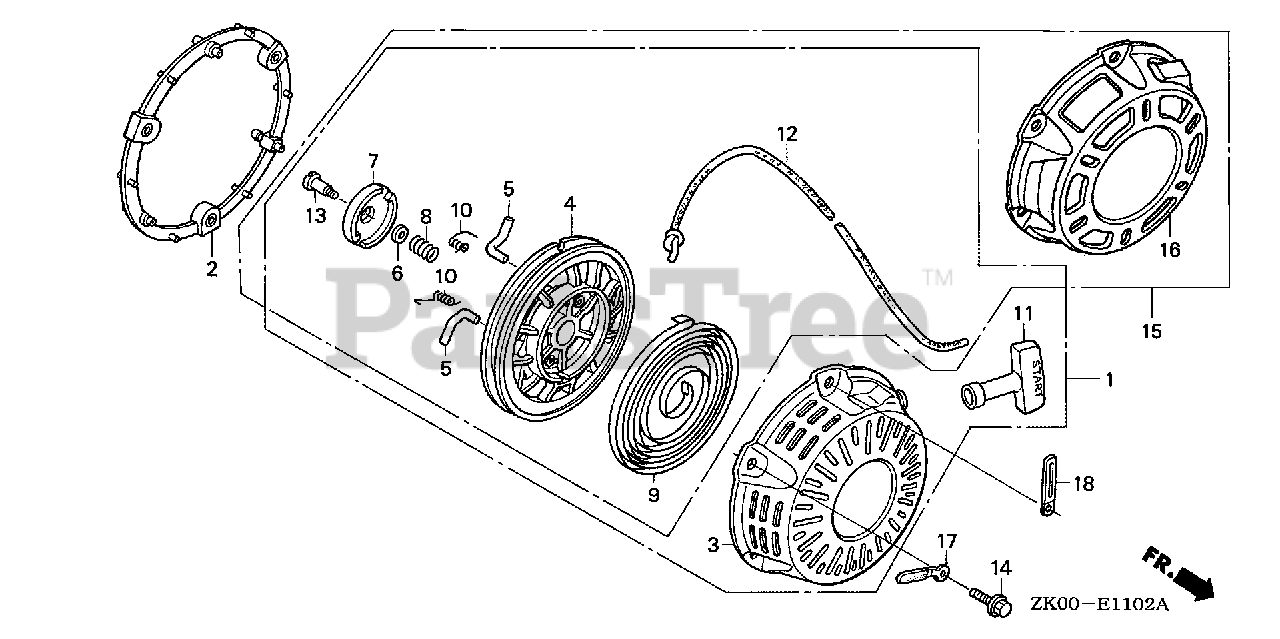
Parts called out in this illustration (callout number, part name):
1	STARTER ASSY., RECOIL *R280* (POWER RED)
2	SPACER, RECOIL STARTER MOUNTING *NH1* (BLACK)
2	SPACER, RECOIL STARTER MOUNTING *R280* (POWER RED)
3	CASE, RECOIL STARTER *R280* (POWER RED)
4	REEL, RECOIL STARTER (BLACK)
5	RATCHET, STARTER
6	PLATE, FRICTION
7	GUIDE, RATCHET
8	SPRING, FRICTION
9	SPRING, RECOIL STARTER
10	SPRING, RETURN
11	GRIP, STARTER
11	KNOB, RECOIL SRARTER
12	ROPE, RECOIL STARTER
13	SCREW, SETTING
14	BOLT, FLANGE (6X18)
